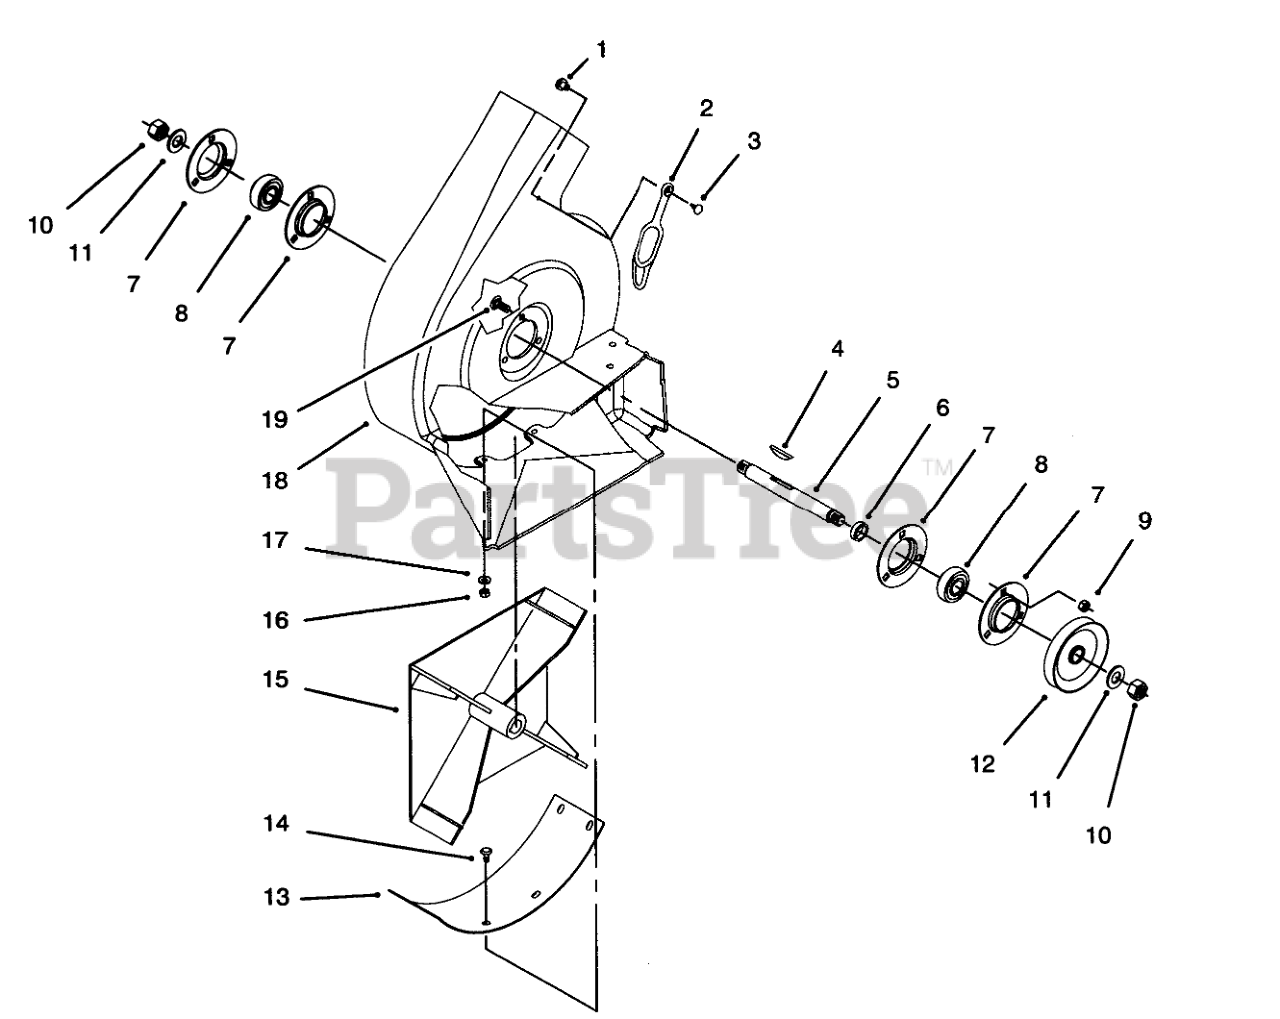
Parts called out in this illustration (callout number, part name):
1	SPACER-INTERLOCK
2	RETAINER-DUCT
3	FASTENER-PANEL
5	SHAFT-BLOWER
6	Spacer
7	FLANGE
8	BEARING-BALL
9	NUT-HF
10	NUT-JAM
11	WASHER-LOCK
12	PULLEY-BLOWER
13	COVER-BLOWER, BOTTOM
14	SCREW-CARRIAGE
15	Impeller
16	NUT-LOCK, NI
17	WASHER-FLAT
18	HOUSING-VAC, BLOWER
19	SCREW-CARR
